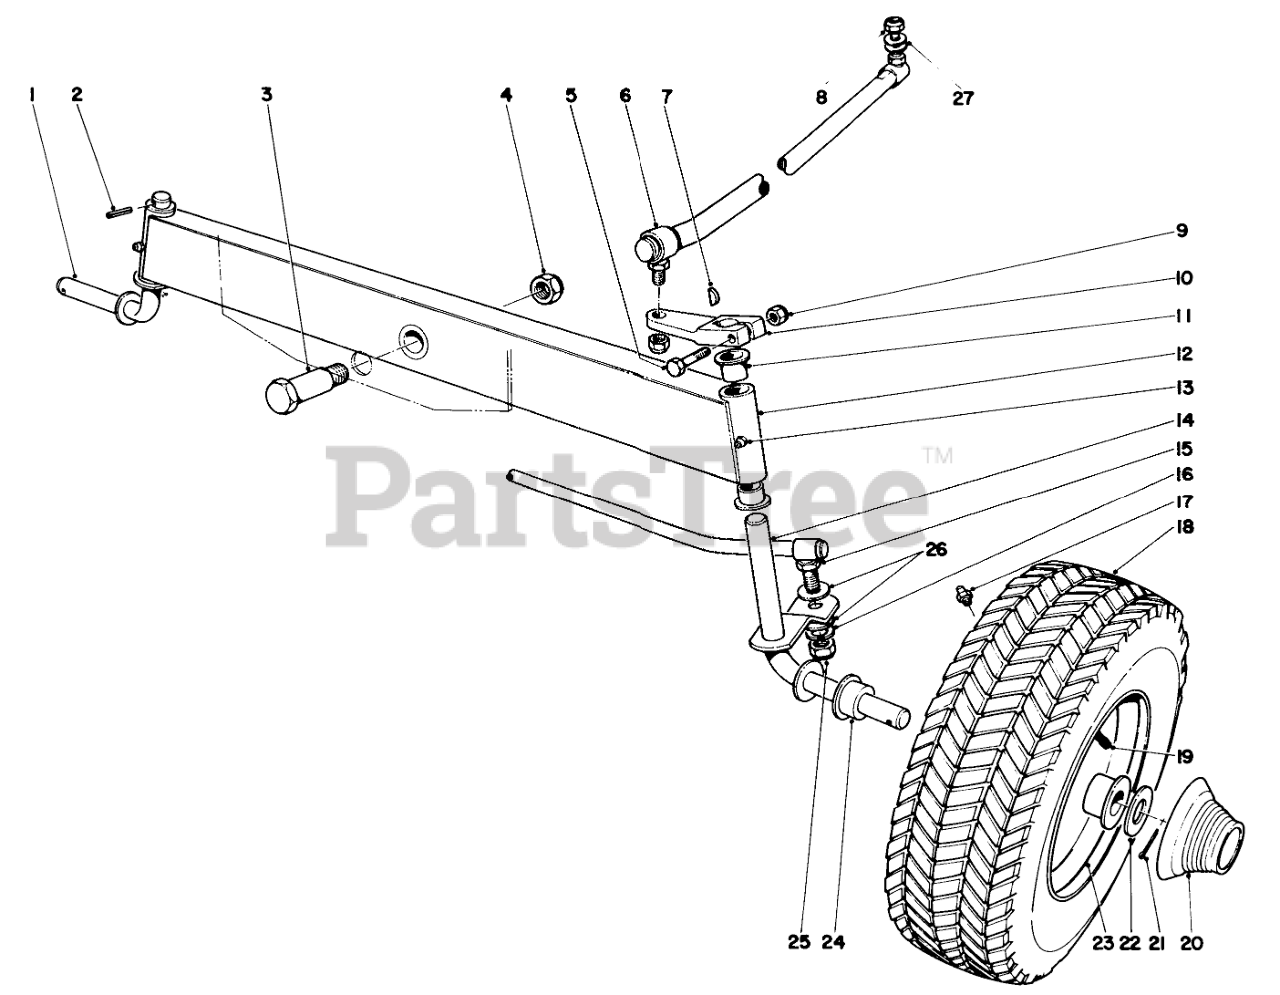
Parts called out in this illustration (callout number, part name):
1	Spindle
2	PIN-SPRING
3	Shoulder Bolt
5	SCREW-HH
6	Drag Link
7	KEY-WOODRUFF
8	Nut
10	Arm Drag Link
11	3/4IDX1LG FLANGE BSHG
12	Front Axle Incl. Ref. #11
13	GREASE FITTING
14	Spindle L.H.
15	Tie Rod
16	Lockwasher
17	FITTING-GREASE
19	Valve Stem
20	FRONT HUB CAP
21	PIN-COTTER
22	Washer
23	Rim
24	Bushing
25	NUT-HEX
26	WASHER
27	Wheel Assy.
